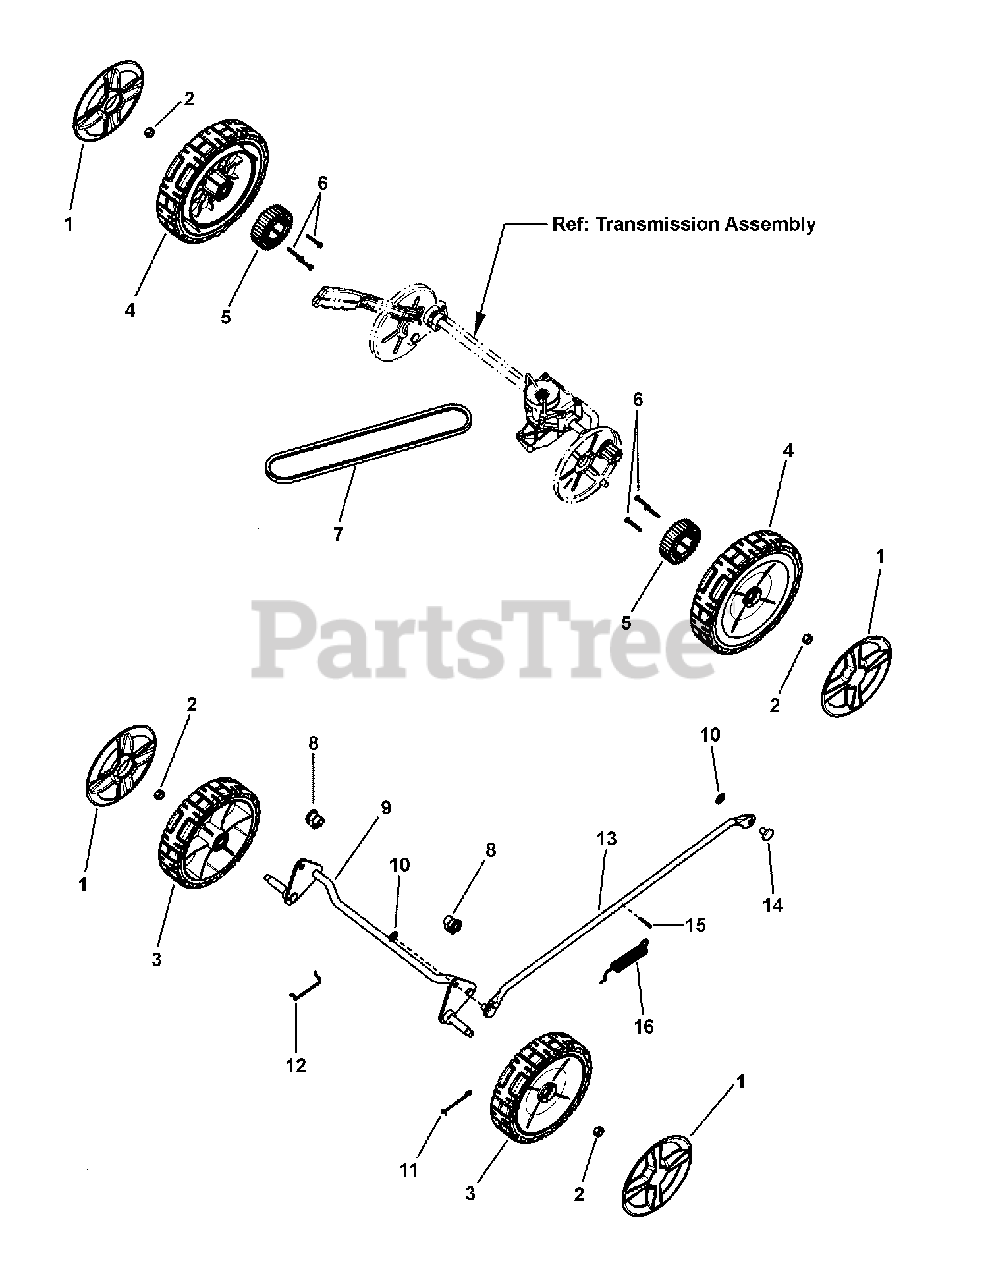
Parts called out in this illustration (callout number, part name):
1	HUBCAP, 8" & 9" Wheel Spoked Cool Gray
2	NUT, 3/8-16 Hex Center Lock
3	ASSY, Wheel, 8 x 2 Idle, Charcoal Gray
4	ASSY, 9" Wheel & Bearing, Charcoal Gray
5	GEAR, External Wheel
6	SCREW, #8 x 1-1/4, Hex Washer Self-Tap (Hi-Lo)
7	BELT, Traction Drive
8	BUSHING, Front Axle
9	WELDMENT, Front Axle
10	WHEEL RETAINER, 3/8
11	SPRING, Axle Retaining, LH
12	SPRING, Axle Retaining, RH
13	WELDMENT, Tie Bar
14	PIN, 3/8" X 5/8"
15	COTTER PIN, 1/8 x 3/4
16	SPRING, Tie Bar
